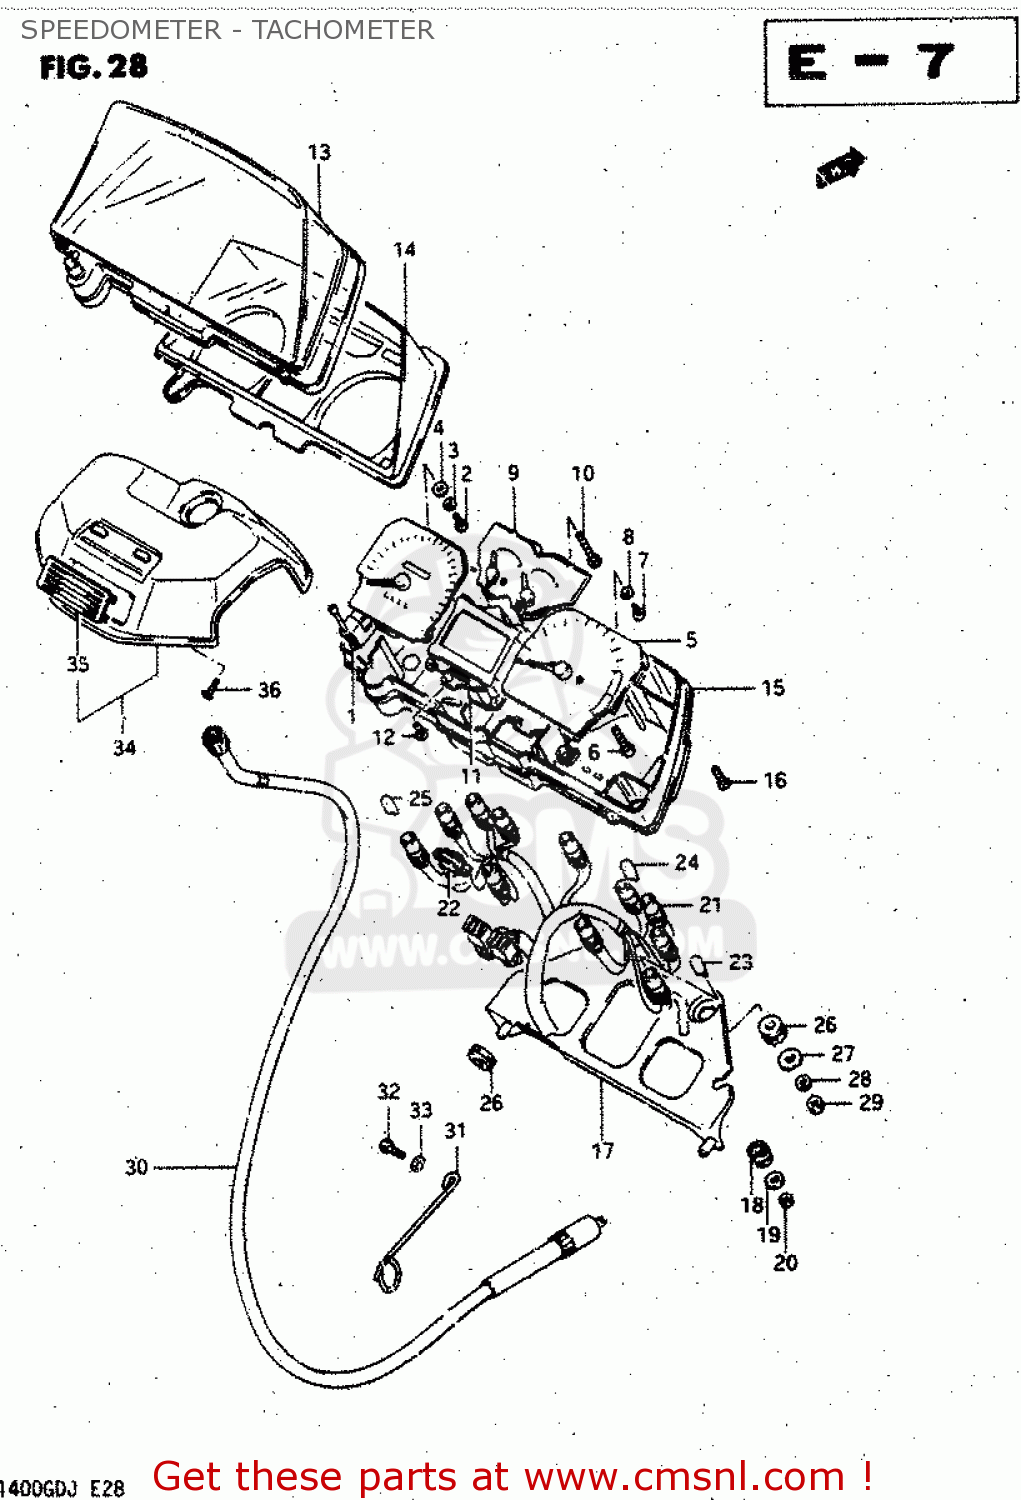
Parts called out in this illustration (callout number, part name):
1	SPEEDOMETER (KILO)
2	SCREWM4X0.7X10
3	LOCK WASHER
4	WASHER
5	METER,TACHOMETER
6	SCREW
7	SCREW
8	LOCK WASHER
9	FUEL & TEMP METER
10	SCREW(3X22)
11	UNIT,INDICATOR
12	SCREW
13	HOOD,METER
14	PANEL,METER
15	CASE,METER
16	SCREW,L:12
17	BRACKET,METER
18	CUSHION
19	WASHER (5.5X16X1.2)
20	NUT
21	SOCKET,METER
22	LEAD SWITCH
23	BULB(12V3.4W,T10)
24	BULB(12V1.7W,T10,WB121)
25	BULB 12V 1.7W
26	CUSHION
27	WASHER
28	WASHER,LOCK
29	NUT
30	CABLE ASSY,SPEEDOMETER
31	CLAMP,SPEEDOMETER CABLE
32	BOLT
33	WASHER
34	SWITCH ASSEMBLY,TIME ADJUST
35	LOUVER
36	SCREW
